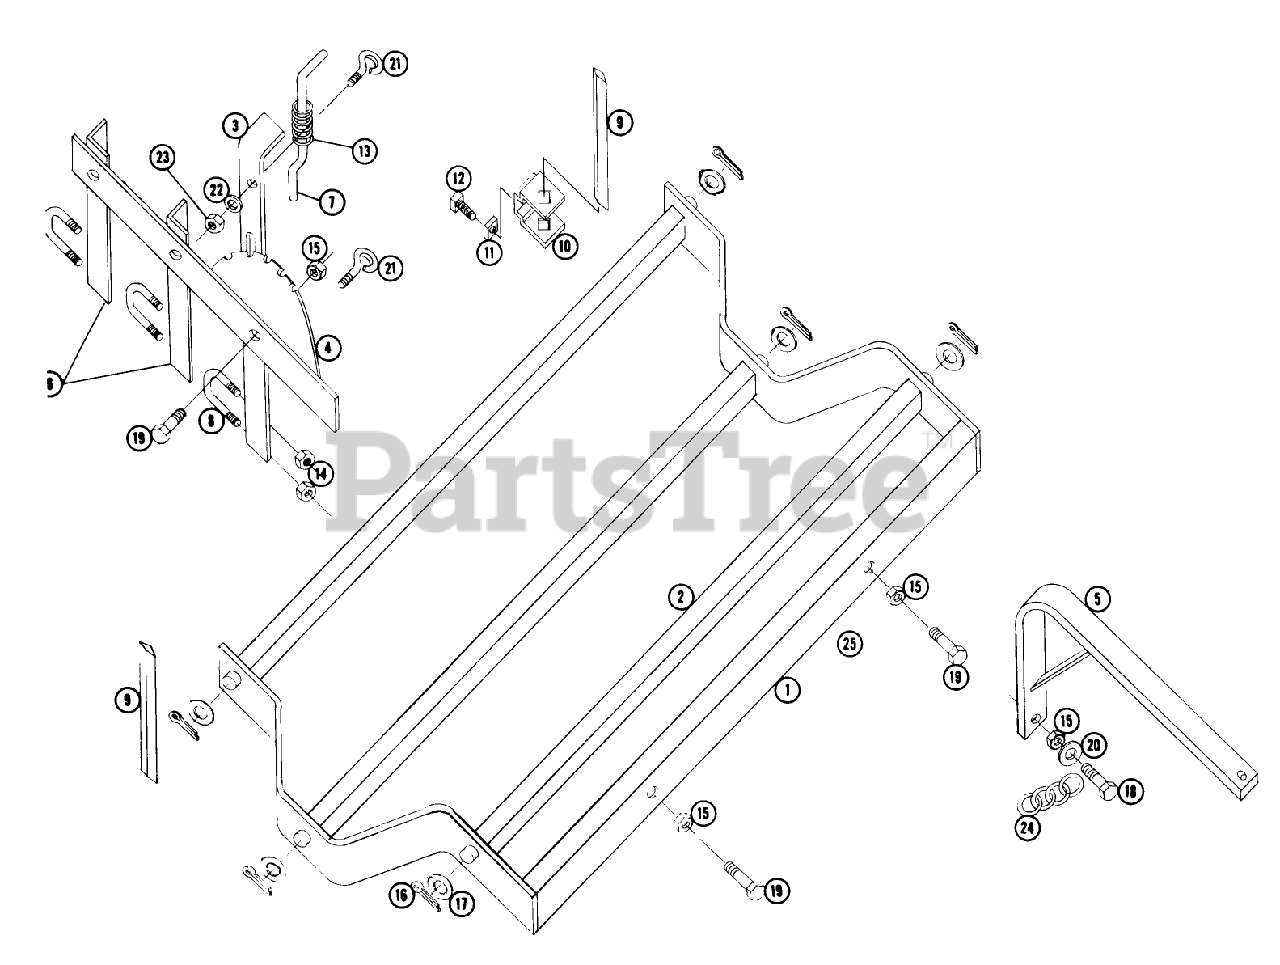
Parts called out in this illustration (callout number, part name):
1	Frame Assembly
2	Channel Assembly
3	Handle Assembly
4	Sector Assembly
5	Hitch
6	Adjusting Angle
7	Locking Pin
8	"U" Bolt
9	Spike
10	Spike Clamp
11	Sq. Nut-3/8-16
12	Screw-Set
13	Spring
14	Nut
15	Nut
17	Washer
18	BOLT
19	Bolt
20	Washer
21	Eyebolt
22	WASHER
23	Nut
24	Chain
24	DECAL-WHEEL HORSE
